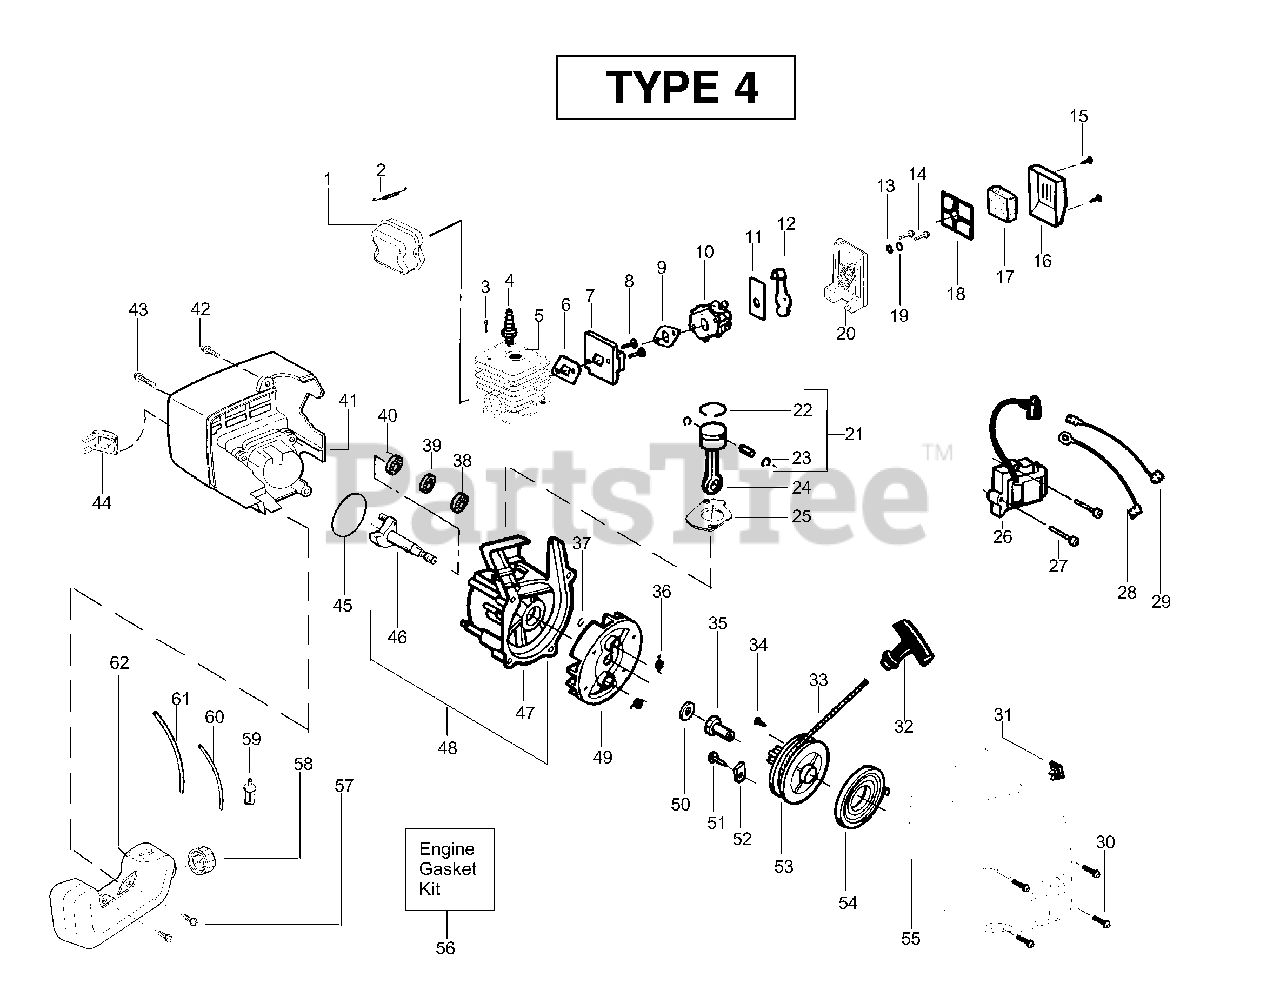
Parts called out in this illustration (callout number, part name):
1	Kit - Muffler
2	Muffler Spring
3	Screw-Cylinder
4	Spark Plug (RCJ 6Y)
5	Kit - Cylinder
6	Gasket-Cyl/Carb.(kit)
7	Adaptor-carb.
9	Gasket-Carb.(kit)
10	Kit-Carb. (WA-226)
10	Kit-Carb. (WT-631)
11	Plate-Choke Mounting
12	Lever-Choke
16	Cover-Air Box
17	Foam-Air Filter
18	Plate-Air Filter Support
19	Spacer-Choke
21	Kit - Piston
22	Piston Ring
23	Retainer-Piston Pin
24	Assy-Connecting Rod
25	Gasket-Cylinder(kit)
26	Ignition Module
28	Assy-Ground Wire
29	Assy-Leadwire
30	Screw
31	Kit-Switch
32	Handle-Starter
33	Kit - Rope
35	Coupling-Drive
36	Spring-Starter Dog
37	Retain. Ring-C'shaft
38	Bearing-Outer
39	Kit-Seal C'case
40	Bearing-Inner
43	Screw
44	Guard-Muffler
45	O-Ring-C'case(kit)
46	Assy-Crankshaft
47	Kit-Crankcase
48	Assy-C'case & C'shaft
49	Assy-Flywheel
50	Washer-Flat
52	Retainer-Pulley
53	Kit-Starter Pulley
54	Spring-Starter
55	Assy-Fan Housing
56	Kit-Engine Gasket
57	Retainer-Tank
58	Assy-Fuel Cap
59	Assy-Fuel Pickup
60	Kit-Fuel Line
61	Kit-Fuel Line
62	Assy-Fuel Tank
